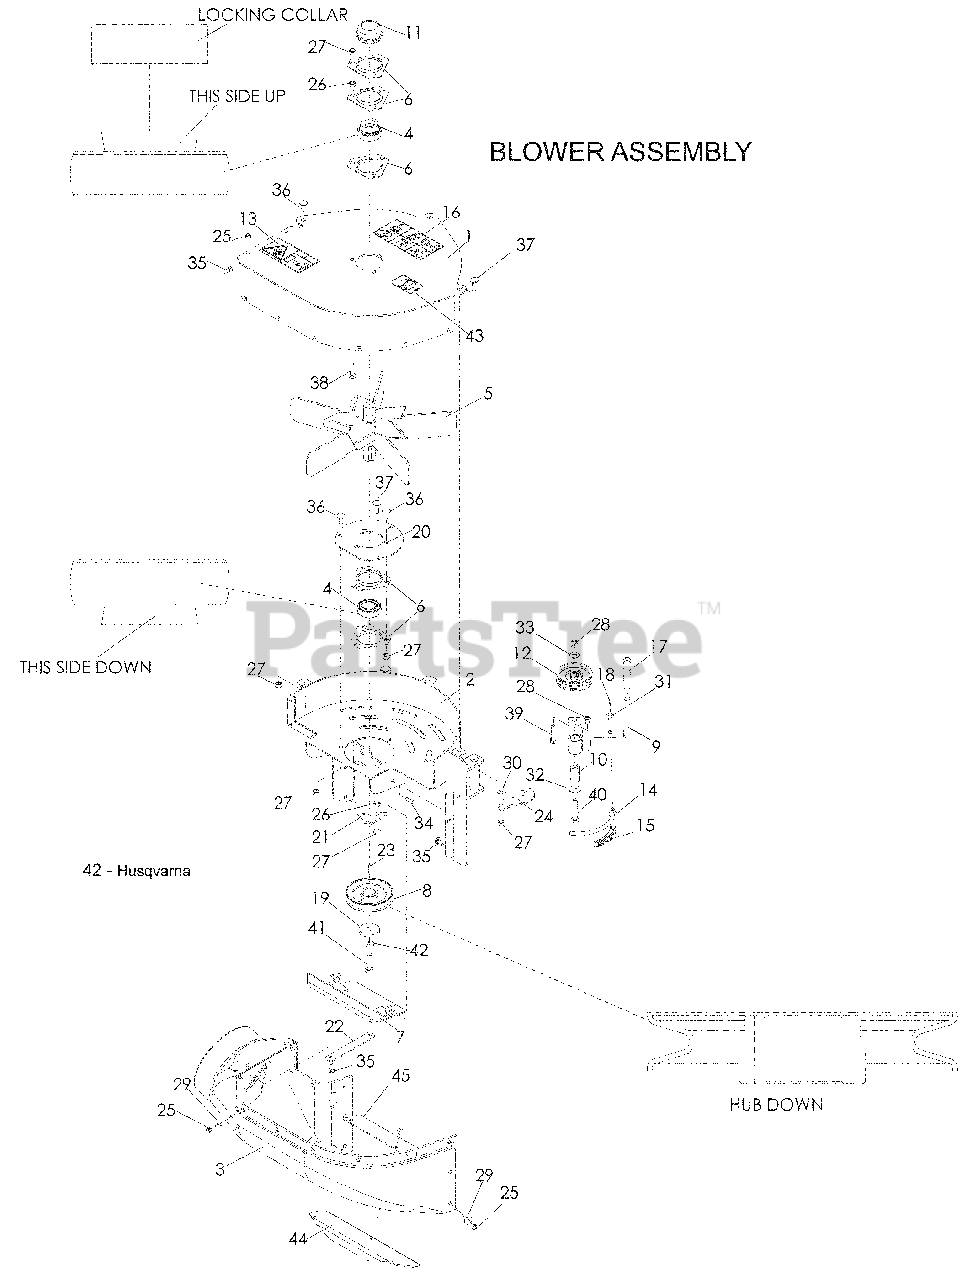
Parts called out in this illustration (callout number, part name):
1	FAN COVER W/DECALS
2	BLOWER HOUSING
3	LOWER HOUSING
7	COVER PLATE
8	SHEAVE, 4"
10	SLEEVE BUSHING
11	CAP, GREASE
13	DECAL, SEVERING
14	SPRING ROD
16	DECAL, WARNING
17	GRIP, VINYL
18	PIN, COTTER 3/32 x ¾
19	HEAVY WASHER
20	BEARING PLATE
21	BELT GUIDE
23	KEY ¼ SQ x ¾
24	IDLER ARM KEEPER
25	NUT ¼-20, THIN, NYLOC
26	NUT 5/16-18
27	NUT 5/16-18 HEX NYLOC
28	NUT 3/8-16 CENTERLOCK
30	WASHER 5/16 STD FLT
31	WASHER 5/16 SAE
32	WASHER 3/8 STD FLT
33	WASHER 3/8 SAE FLT
34	SCREW, ¼-20 x 5/8 BTN
35	RHSNB ¼-20 x ¾ GR2
36	RHSNB 5/16-18 x ¾
37	RHSNB 5/16-18 x 1
38	RHSNB 5/16-18 x 1¼
39	HCS 3/8-16 x 1½
40	HCS 3/8-16 x 2
41	HCS 7/16-20 x 1½
42	LOCKWASHER 7/16
43	DECAL, NO STEP
44	BLOWER SUPPORT
45	PLATE, BLOWOUT
